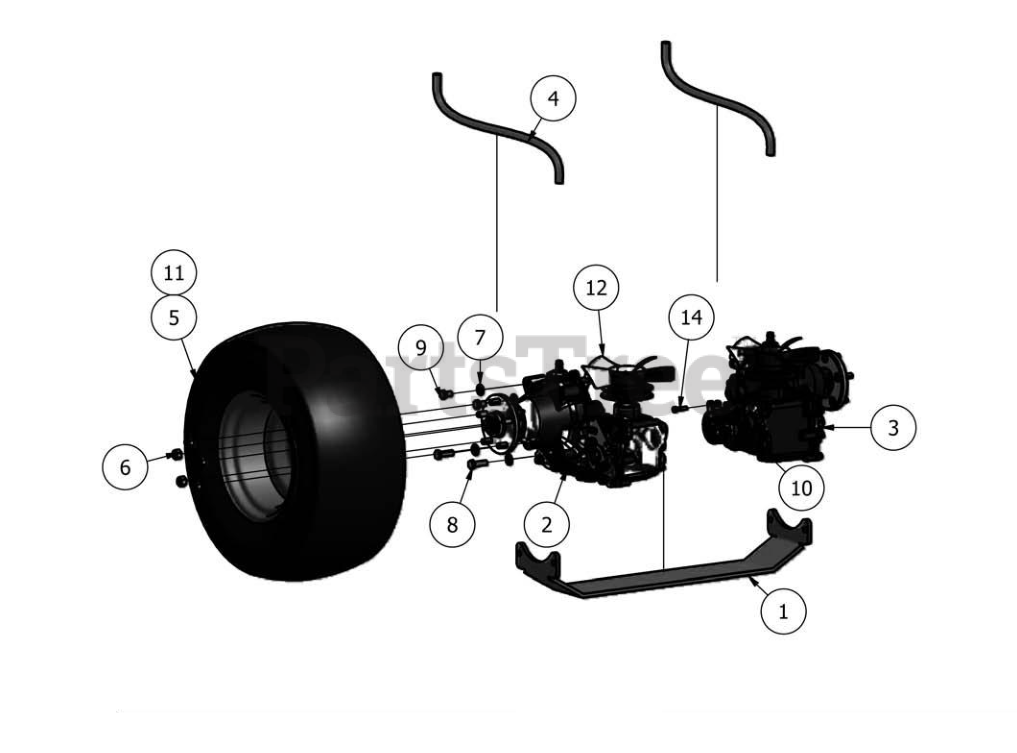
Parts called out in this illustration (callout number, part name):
1	Outlaw TransAxle Cross Brace
2	ZT-5400- Left
3	ZT-5400- Right
4	1/2 Clear Braided Hose
5	24 x 12 x 10 Tire and Wheel
6	Acorn Lug Nut
7	1/2 Lock Washer Zinc
8	1/2-20 x 1-1/2 Grade 5 Hex Bolt Zinc
9	1/2 x 3/4 Bolt
10	5/16-18 Nylon Insert Locknut Zinc Orange Nylon
11	24 x 12 x Tire Only
12	Out Law 5400 Series Fan
